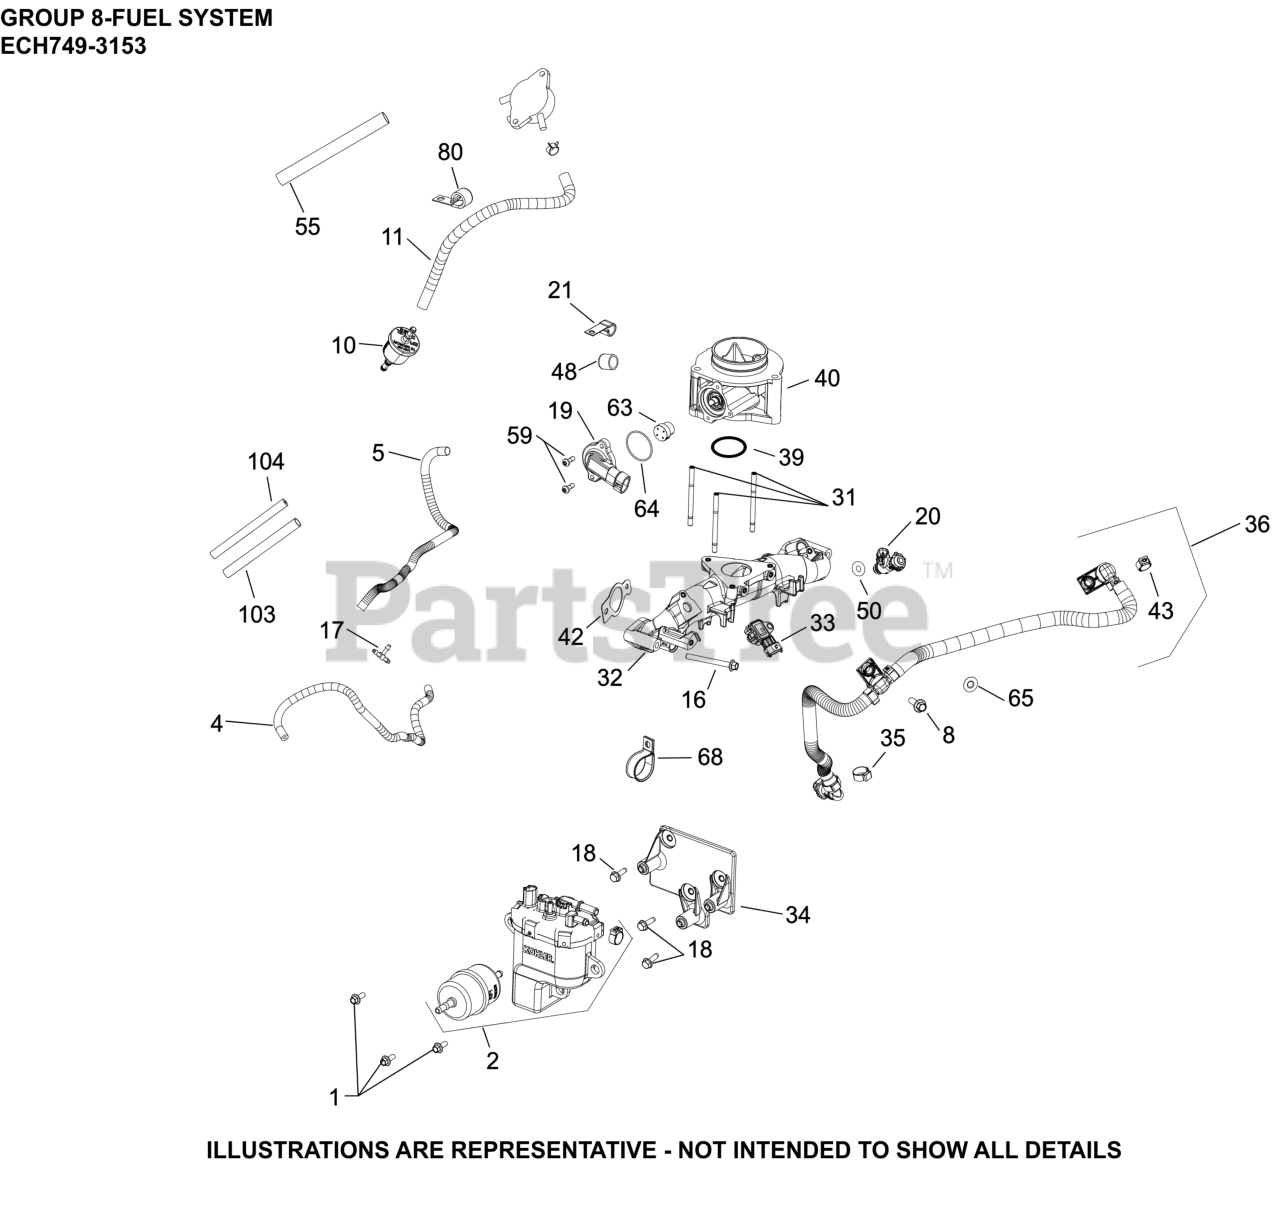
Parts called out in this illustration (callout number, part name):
1	SCREW, FLG M6X1.0X16
2	KIT, FUEL PUMP MODULE
4	HOSE, EVAPORATIVE (15.0)
5	SLEEVE, ANTI-ABRASION
8	SCREW, FLG M6x1.0x20
10	FILTER, FUEL
11	HOSE,LW PERM.FUEL 24.00"-USE 25 111 81-S
16	SCREW, FLG M6X1.0X60
17	TEE CONNECTOR
18	SCREW, THREAD FORMING
19	SENSOR, THROTTLE POSITION
20	INJECTOR, FUEL
21	CLIP, CABLE
31	STUD,M6X1.0X84
32	KIT, MANIFOLD
33	SENSOR, T-MAP
34	BAFFLE, FUEL MODULE
35	CLAMP, HOSE
36	FUEL HOSE ASSEMBLY,ECH680-ECH749
39	O-RING, THROTTLE BODY
40	BODY, THROTTLE ASM (30)
42	KIT, INTAKE MANIFOLD GASKET
43	CLAMP, OETIKER
48	CAP, MASKING
50	KIT, FUEL INJECTOR O-RING
55	SLEEVE, ANTI ABRASION-USE 25 431 12-S
63	MAGNET ASSEMBLY, TPS
64	O-RING, TPS SENSOR
65	CLIP, RETAINER
68	CLAMP, INSULATED
80	CLIP, CABLE (KM)
103	SLEEVE, ANTI-ABRASION
104	HOSE, EVAPORATIVE (4.5)
